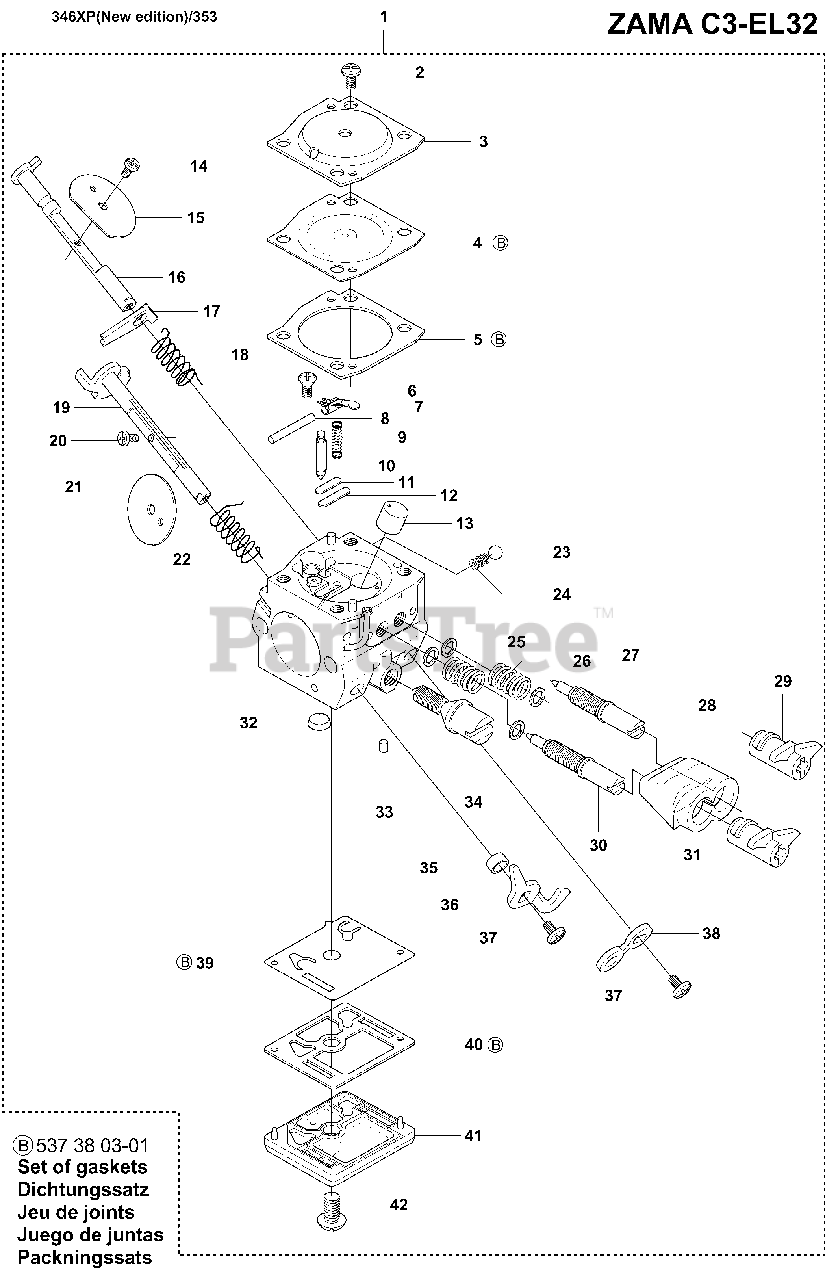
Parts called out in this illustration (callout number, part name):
1	CARBURETOR
4	DIAPHRAGM
5	Gasket
8	PIN FULCRUM
15	CHOKE FLAP
16	CHOKE SHAFT
17	THROTTLE LOCK
19	THROTTLE SHAFT
21	THROTTLE FLAP
26	SPRING
29	LIMITER CAP
30	LOW SPEED NEEDLE
31	LIMITER CAP
34	IDLE SCREW
39	PUMP DIAPHRAGM
40	GASKET
B	GASKET SET
